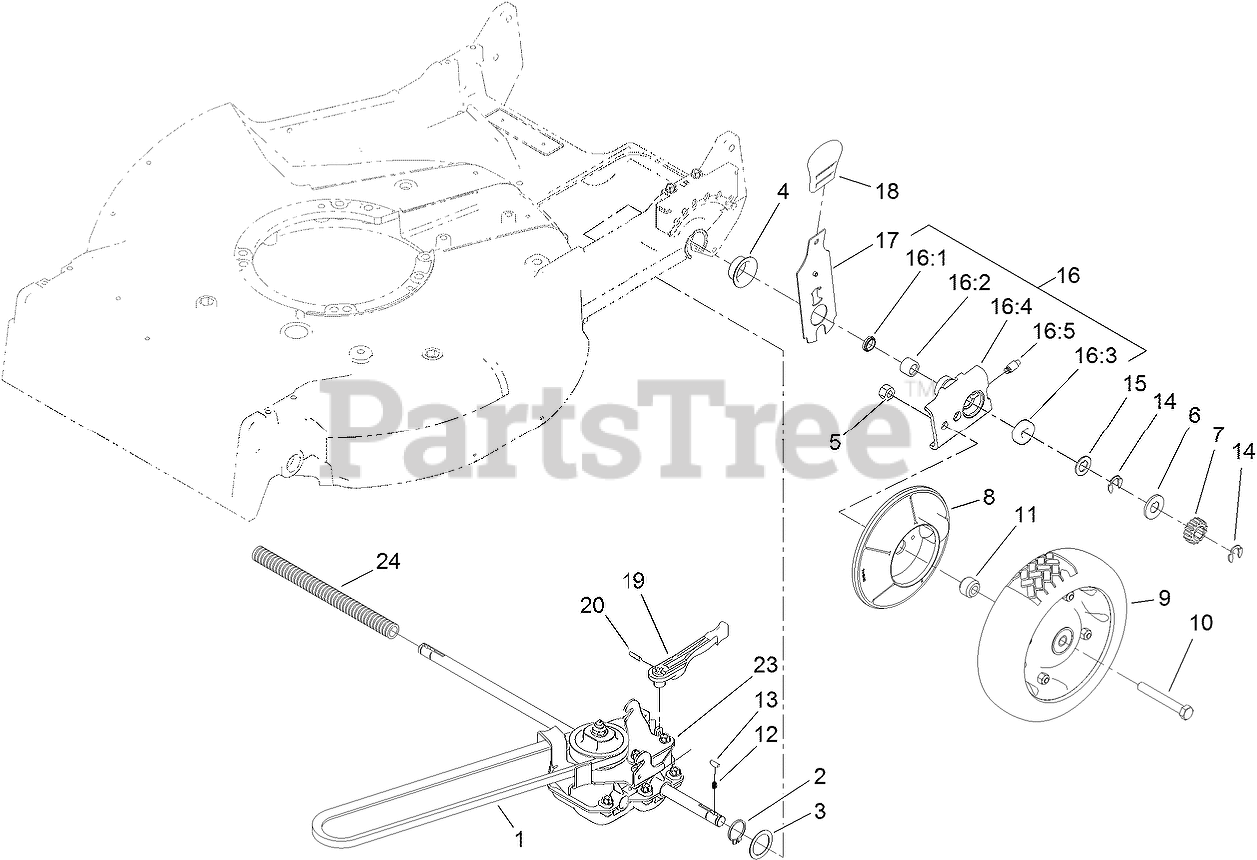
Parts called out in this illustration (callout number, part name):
1	V-BELT
2	RING-RETAINING
3	WASHER
4	CAP-END
5	NUT-LOCK, CONE
6	WASHER-THRUST, OUTER
7	GEAR-PINION
8	COVER-WHEEL
9	WHEEL AND TIRE ASM
10	SCREW-HH
11	SPACER-COVER, WHEEL
12	SPRING-COMPRESSION
14	RING-RETAINING
15	WASHER-THRUST, OUTER
16	PIVOT ARM ASM
16:1	SEAL-OIL
16:2	BEARING-CAGED NEEDLE ROLLER
16:3	BEARING-WHEEL
16:4	Arm-Pivot, Rear
17	REAR SPRING ARM ASM
18	KNOB-HOC
19	LEVER-SHIFT
20	PIN-COIL
23	GEAR CASE ASM
24	COVER-SHAFT, DRIVE
